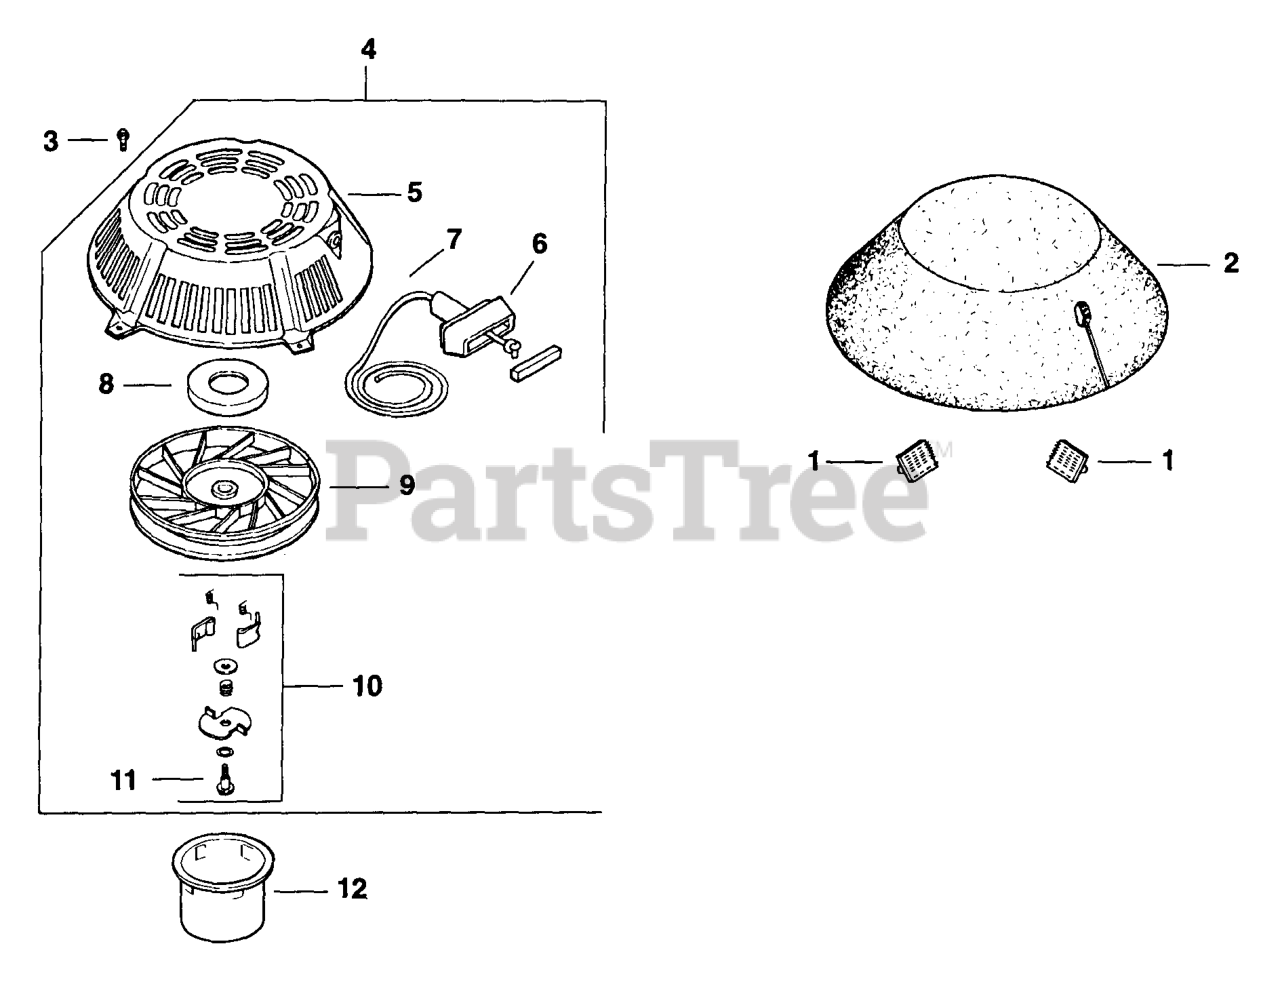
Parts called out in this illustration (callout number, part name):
3	SCREW - USE M-545010
4	STARTER ASSY,RETRACTABLE-USE 12 165 03-S
5	HOUSING - DISCONTINUED
6	HANDLE - USE 25 166 01
7	ROPE - DISCONTINUED
8	SPRING & KEEPER - (#DSC)
9	PULLEY - (#DSC)
10	KIT, DOG REPAIR - (#DSC)
11	SCREW - DISCONTINUED
